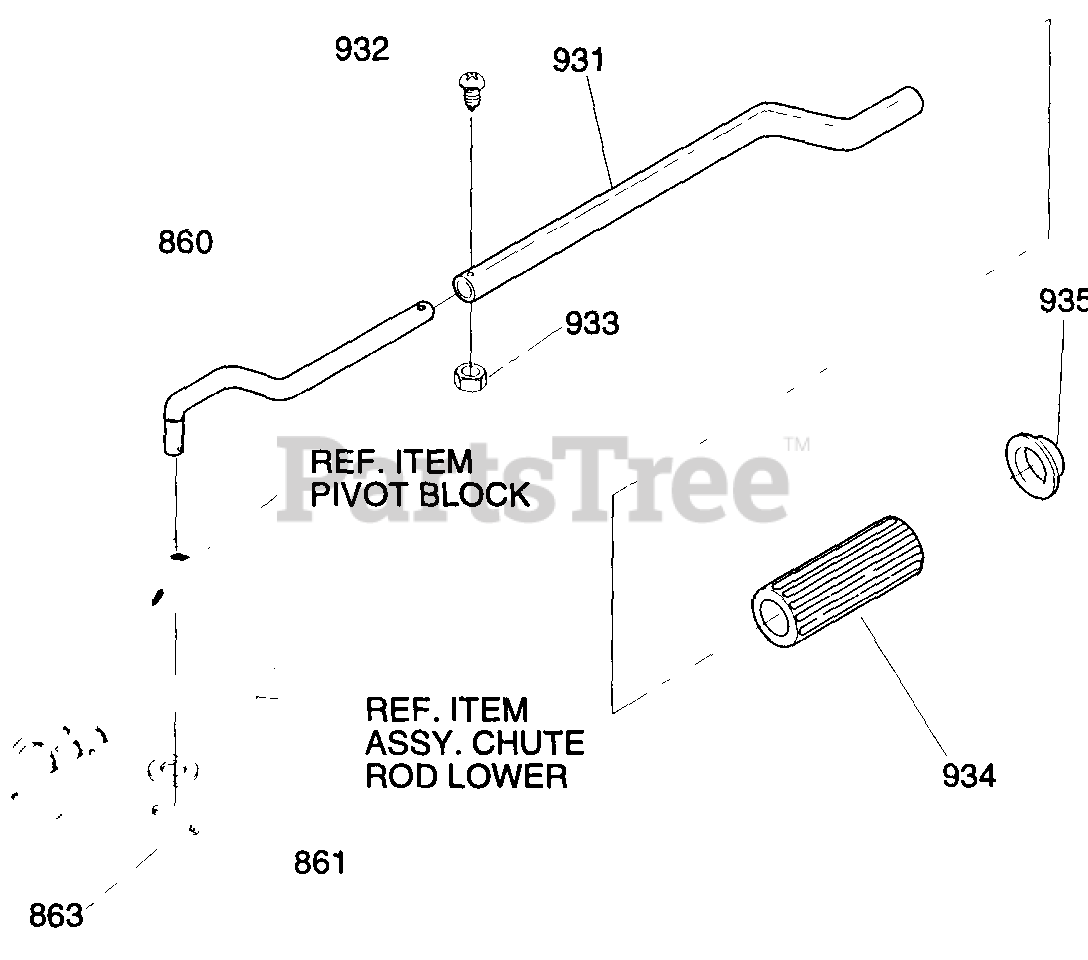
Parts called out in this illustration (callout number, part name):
860	ROD, MID CHUTE CTL
861	WASHER, FLAT .40 X .75 X .02
863	PIN, COTTER .090 DIAX .75 LG
931	ROD CHUTE CTRL UPR, ASSY
932	SCREW, 10-32 X .88 SLTRHD
933	NUT, #10-32 CTRLK
934	KNOB, CHUTE CRANK
935	NUT, PUSH, FITS 3/8 DIA
